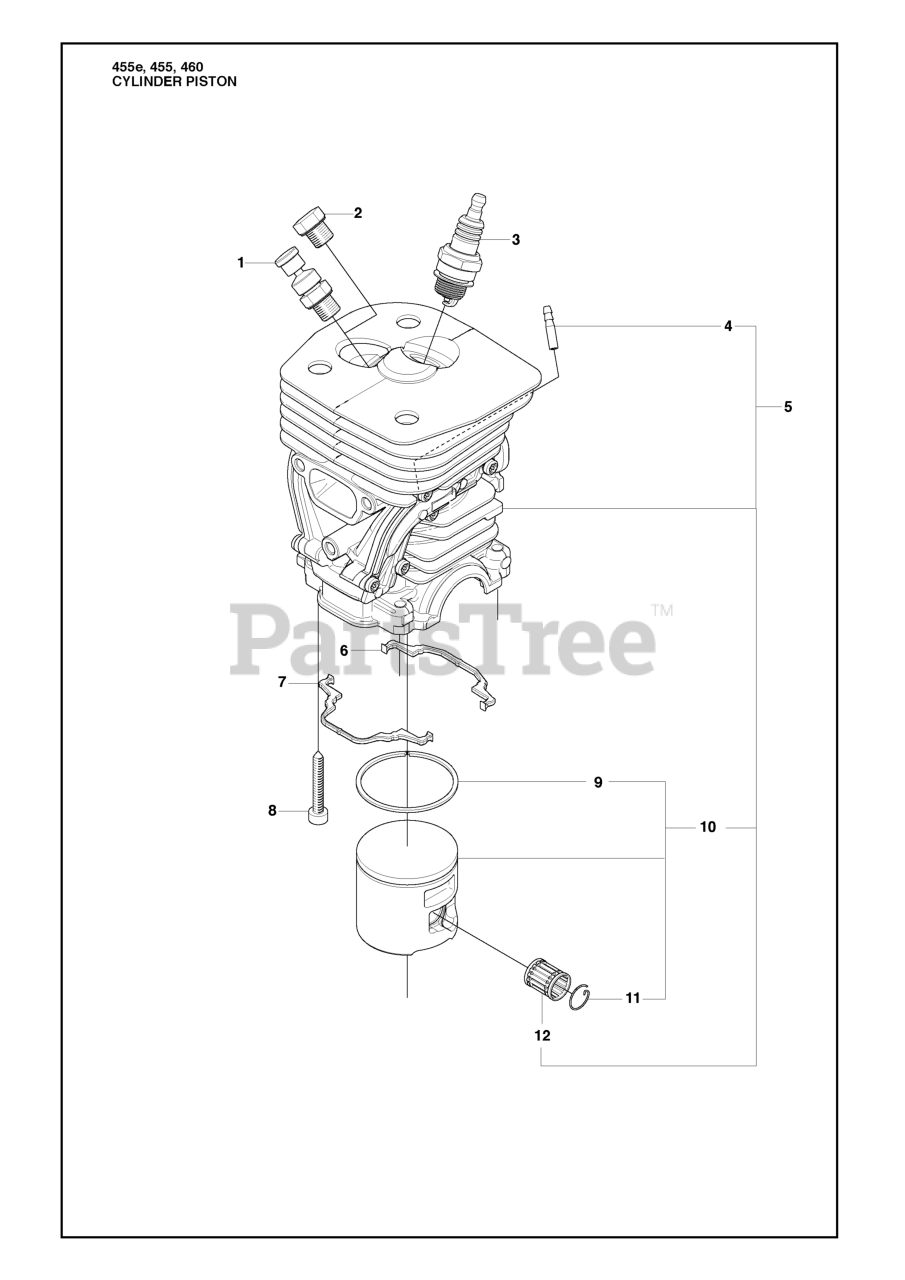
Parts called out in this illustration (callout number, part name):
2	CYLINDER PLUG
3	SPARK PLUG RCJ7Y
5	CYLINDER
9	PISTON RING
10	PISTON CPL.
10	PISTON
11	WRIST PIN CLIP
12	SUPPORT BUSHING
